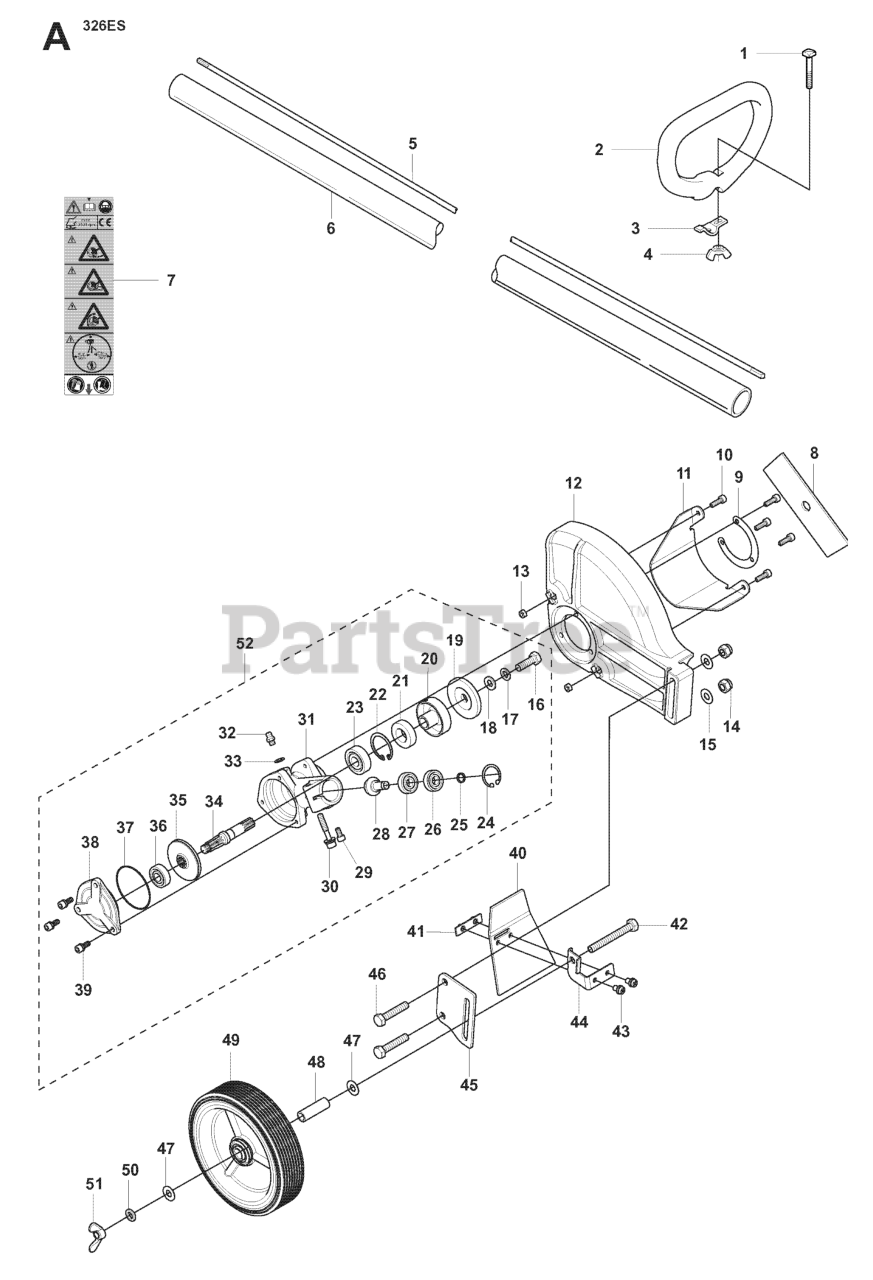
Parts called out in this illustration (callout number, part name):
2	HANDLE, LOOP
3	HOLDER
5	DRIVE SHAFT
6	DRIVE TUBE ASSEMBLY
7	LABEL WARNING
8	BLADE 7.52X2X.125
10	BOLT M5 X L16 ALLEN
11	PLATE, PROTECTOR
14	NUT
16	BOLT M8 X L25 L/H
19	HOLDER (B)
20	HOLDER (A)
24	RP_RING
29	BOLT M5 X L10 ALLEN BOLT
30	BOLT M6 X L35 ALLEN
39	BOLT M5 X L14 ALLEN
42	BOLT M8 X L65
43	BOLT M5 X L10
45	MAIN BRACKET
46	BOLT M8 X L40
51	RP_NUT
52	GEARCASE ASSY
